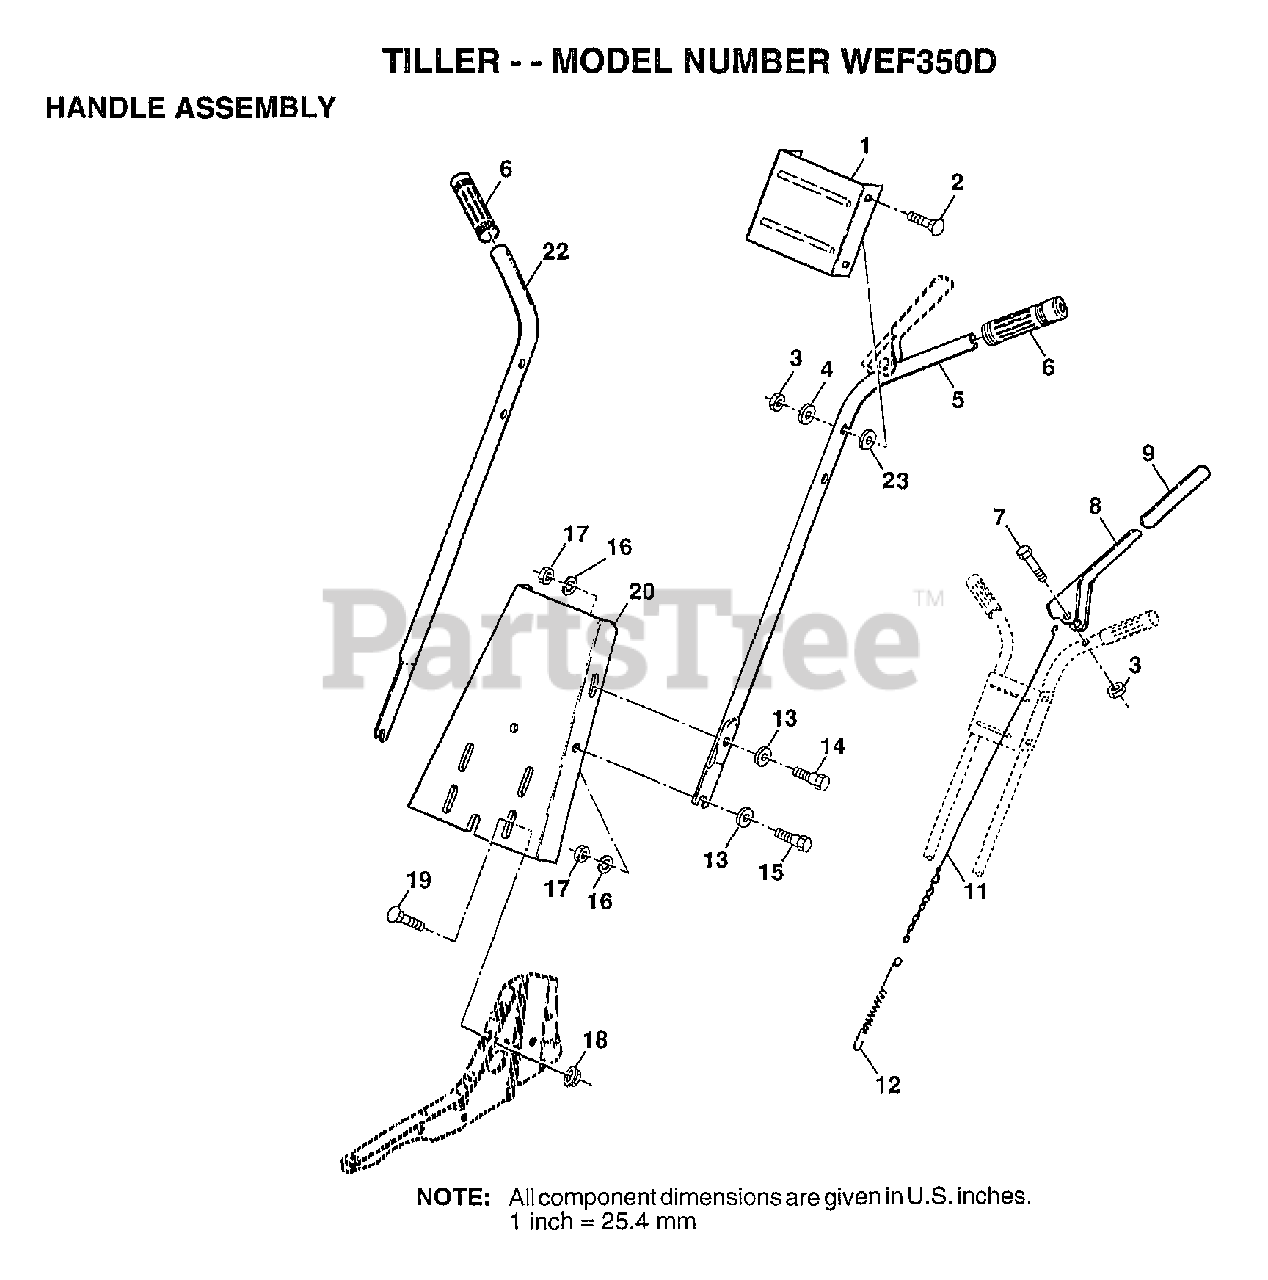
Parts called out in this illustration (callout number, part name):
1	PANEL.CNTRL.HDLE.
2	BOLT
4	WASHER
5	HANDLE LH
7	BOLT.HEX.5/16-1.5
9	GRIP T
12	SPRING EXT TI
13	WASHER
15	BOLT
16	LOCKWASHER
17	NUT.HEX.5/16-18
18	NUT
19	BOLT
20	PANEL.HANDLE.TILL
22	HANDLE RH
23	WASHER
